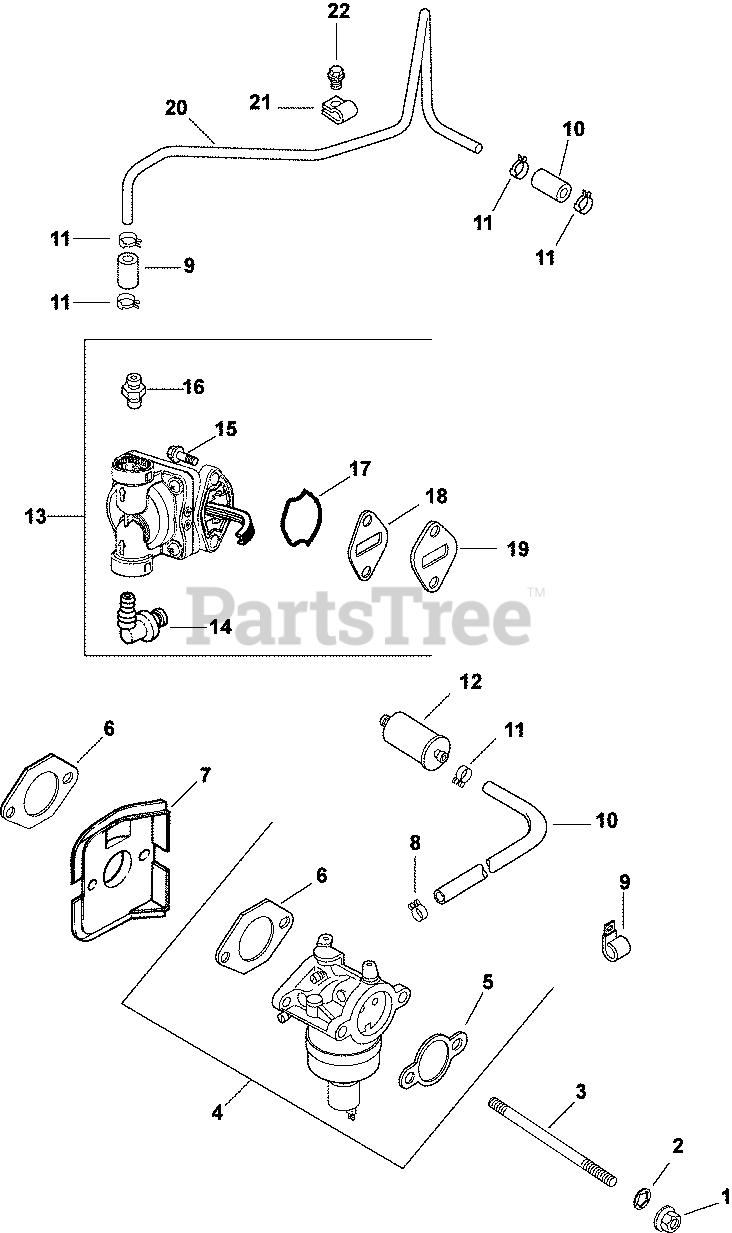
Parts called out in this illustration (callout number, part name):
1	NUT, FLG M6X1.0
2	WASHER, INT TOOTH LOCK 1/4"
3	STUD,M6X1.0X116
4	KIT, CARBURETOR
5	GASKET, AIR CLEANER BASE
6	GASKET, CARBURETOR
7	DEFLECTOR, HEAT
8	CLAMP, BAND SPRING HOSE-(#2523737S)
9	CLIP, CABLE
10	HOSE,LW PERM.FUEL 24.00"-USE 25 111 81-S
11	CLAMP, HOSE (KM)-USE 25 237 31-S
12	FILTR,FUEL 75 MICRON (GRAVTY FEED)
13	KIT, FUEL PUMP
14	CONNECTOR, 90 DEG. HOSE
15	SCREW, LBD SKT M6x1.0x20-(#25086403S)
16	KIT, STRAIGHT FITTING
17	O-RING, FUEL PUMP
18	GASKET, FUEL PUMP
19	SPACER, FUEL PUMP
20	LINE, FUEL
21	CLIP, TUBE & WIRING (KM)
22	SCREW, FLG THD FRM M5X.8X10
